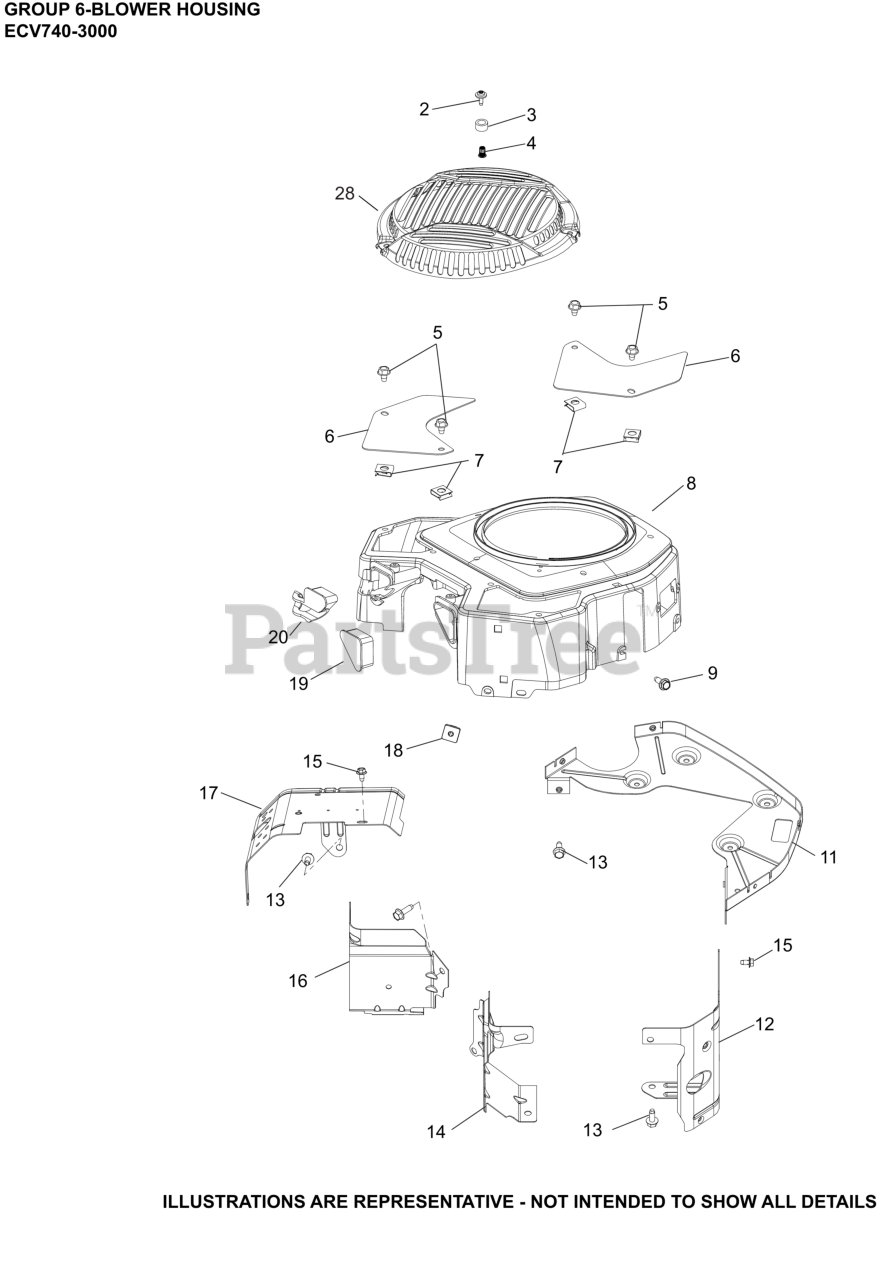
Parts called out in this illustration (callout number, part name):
2	SCREW, SEMS
4	INSERT, THREADED (M5)
5	SCREW, THREAD FORMING
6	KIT, ACCESS PANEL
7	CLIP, BAFFLE MOUNTING
8	HOUSING, BLOWER
9	SCREW, THREAD FORMING
11	PLATE, BACKING
11	KIT, BACKING PLATE
12	BAFFLE LEFT BARREL
13	SCREW, THREAD FORMING
14	BAFFLE, VALLEY #2 CYLINDER
15	SCREW, THREAD FORMING
16	BAFFLE, VALLEY #1 CYLINDER
17	KIT, RIGHT BARREL
18	NUT, PLASTIC
19	COVER, BLOWER HOUSING
20	COVER, BLOWER HOUSING
28	GUARD, GRASS SCREEN (METAL)
NI	STRAP, LIFTING
